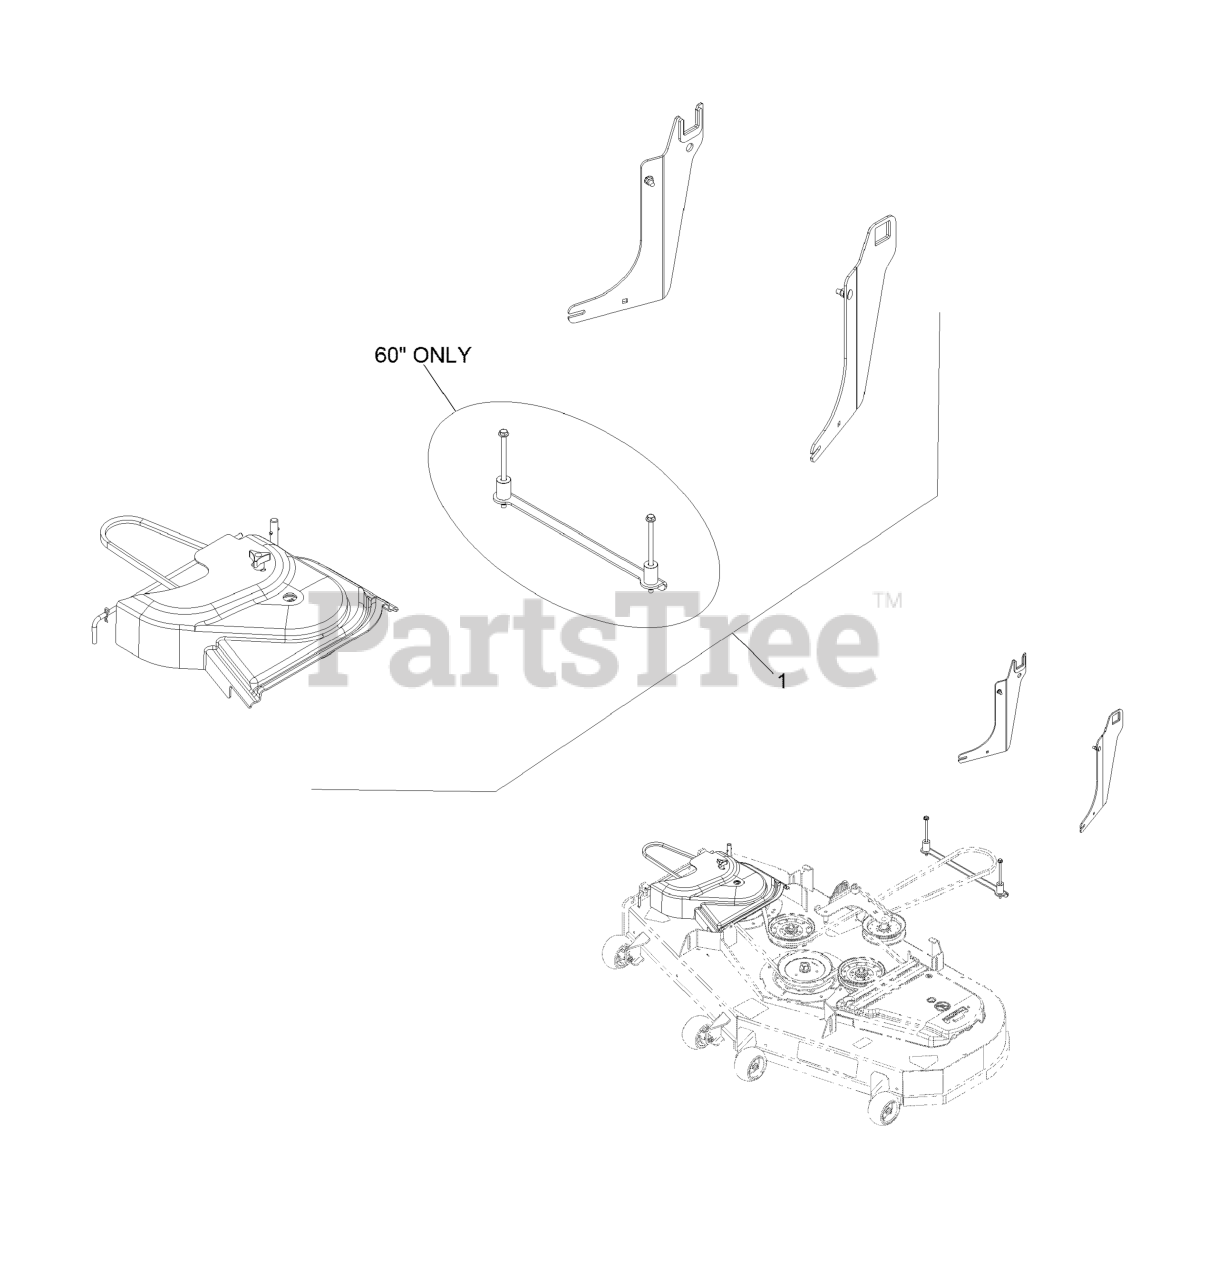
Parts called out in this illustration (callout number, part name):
1	Kit-Completing Qsp 44 Uve
1	Kit-Completing Qsp 48 Uve
1	Kit-Completing Qsp 52 Uve
1	Kit-Completing Pi 44 Uve
1	Kit-Completing Pi 48 Uve
1	Kit-Completing Pi 52 Uve
1	Kit-Completing Pn60 Uve
